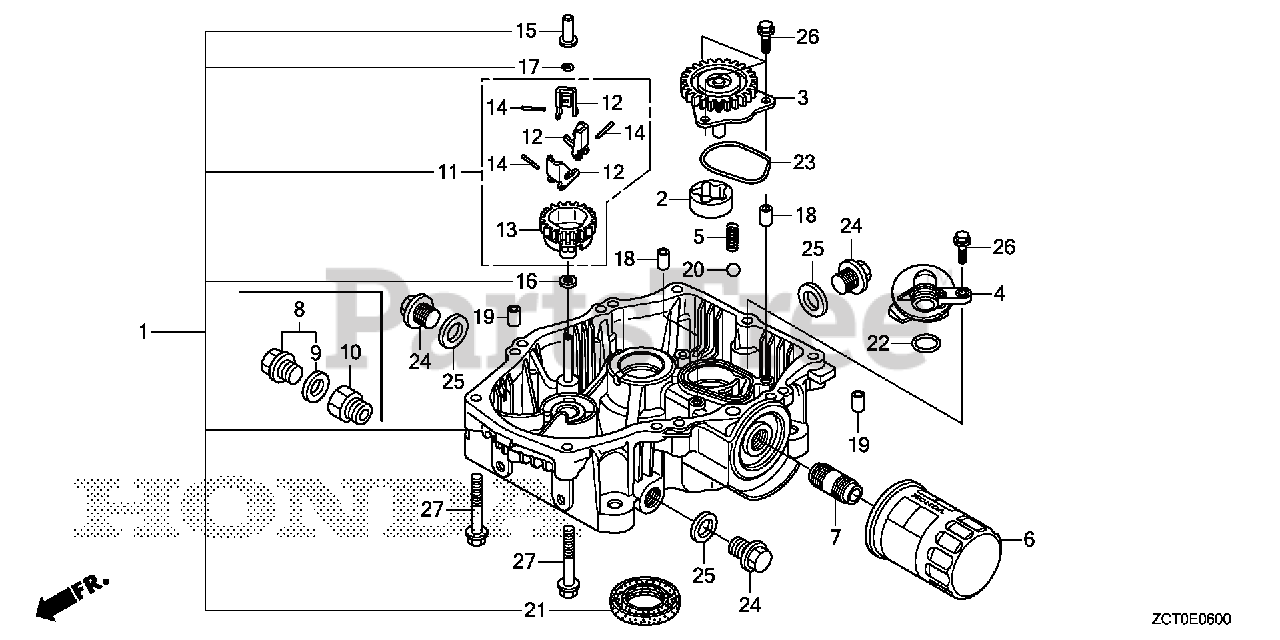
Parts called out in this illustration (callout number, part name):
1	PAN ASSY., OIL
2	ROTOR, OIL PUMP (OUTER)
3	GEAR, OIL PUMP
4	STRAINER, OIL
5	SPRING, RELIEF VALVE
6	FILTER, OIL (FILTECH TOYO ROKI) (SOLD IN MULTIPLES OF 30)
6	FILTER, OIL (FILTECH TOYO ROKI) (SOLD INDIVIDUALLY)
7	HOLDER, OIL FILTER
11	GOVERNOR ASSY.
12	WEIGHT, GOVERNOR
13	HOLDER, GOVERNOR WEIGHT
14	PIN, GOVERNOR WEIGHT
15	SLIDER, GOVERNOR
16	WASHER (6X16)
17	CLIP, GOVERNOR HOLDER
18	PIN, DOWEL (8X10)
19	PIN, DOWEL (8X14)
20	BALL, STEEL (#15) (15/32)
21	OIL SEAL (38X58X9)
22	O-RING (14.8X2.4)
23	O-RING, OIL PUMP
24	BOLT, DRAIN PLUG (20MM)
25	WASHER, DRAIN PLUG (20MM)
26	BOLT, FLANGE (6X20)
27	BOLT, FLANGE (8X45)
